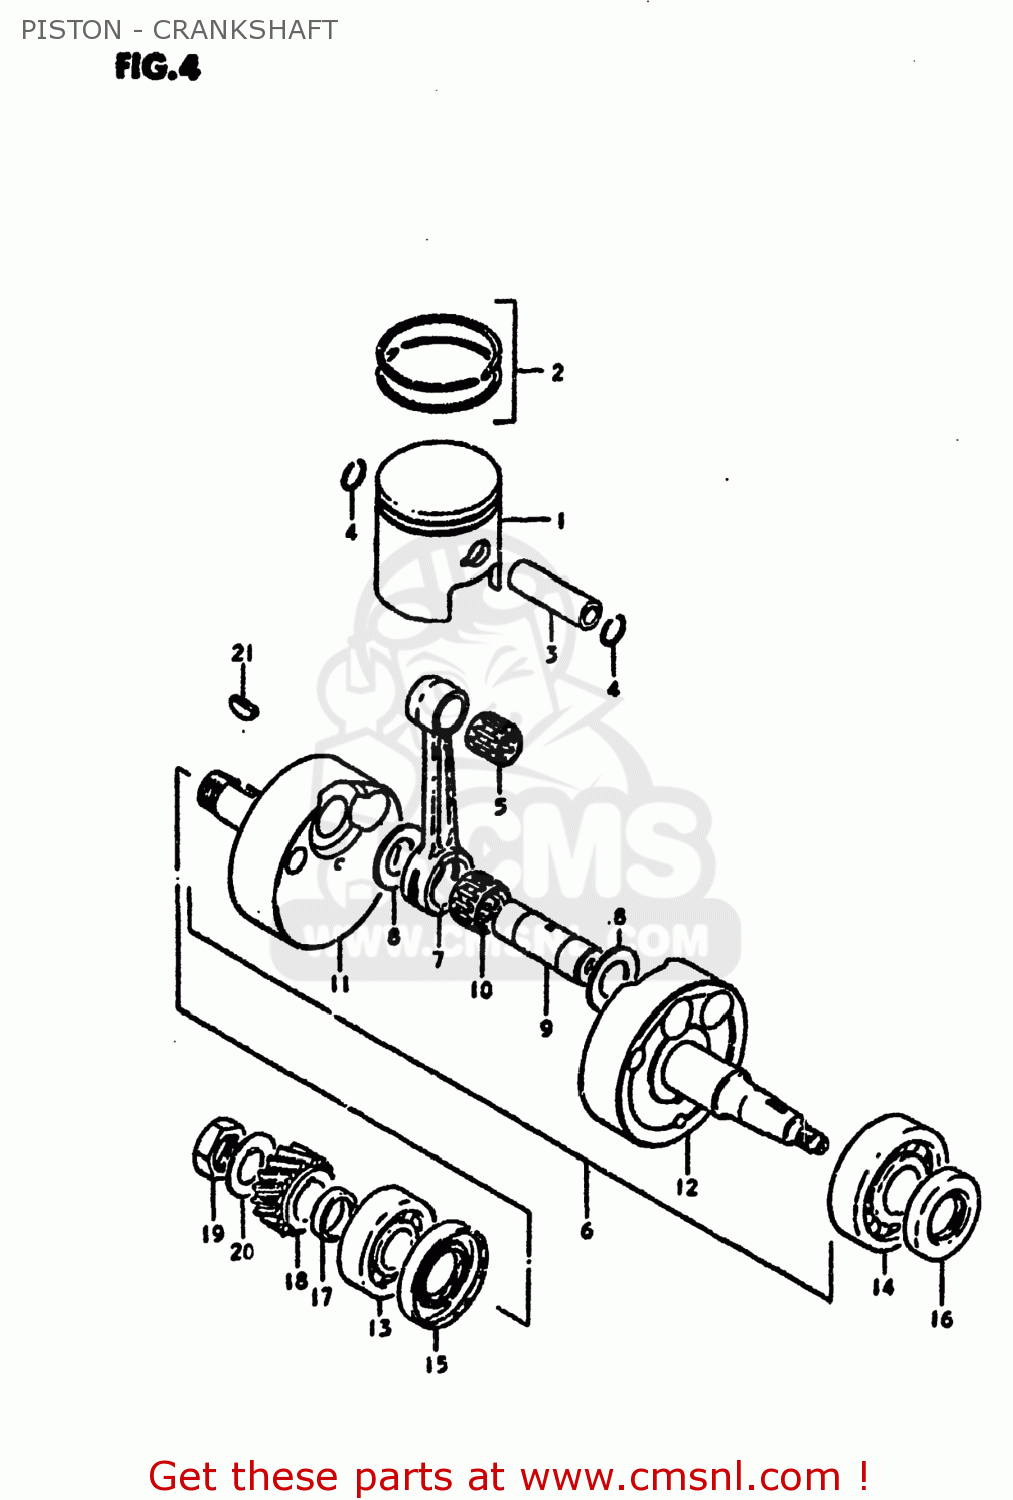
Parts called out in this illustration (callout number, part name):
1	PISTON
2	RING SET,PISTON
3	PIN,PISTON
4	RING,SNAP 14MM
5	BEARING
6	CRANKSHAFT ASSEMBLY
7	CONNECTING ROD
8	WASHER(19X32X1)
9	PIN,CRANK
10	BEARING
11	CRANKSHAFT,R
12	CRANKSHAFT,LEFT
13	BEARING
14	BEARING(25X62X17)
15	SEAL,OIL(26X52X8)
16	OIL SEAL
17	SPACER(20X28X7)
18	GEAR,PRIMARY DRIVE
19	NUT
20	WASHER
21	KEY
